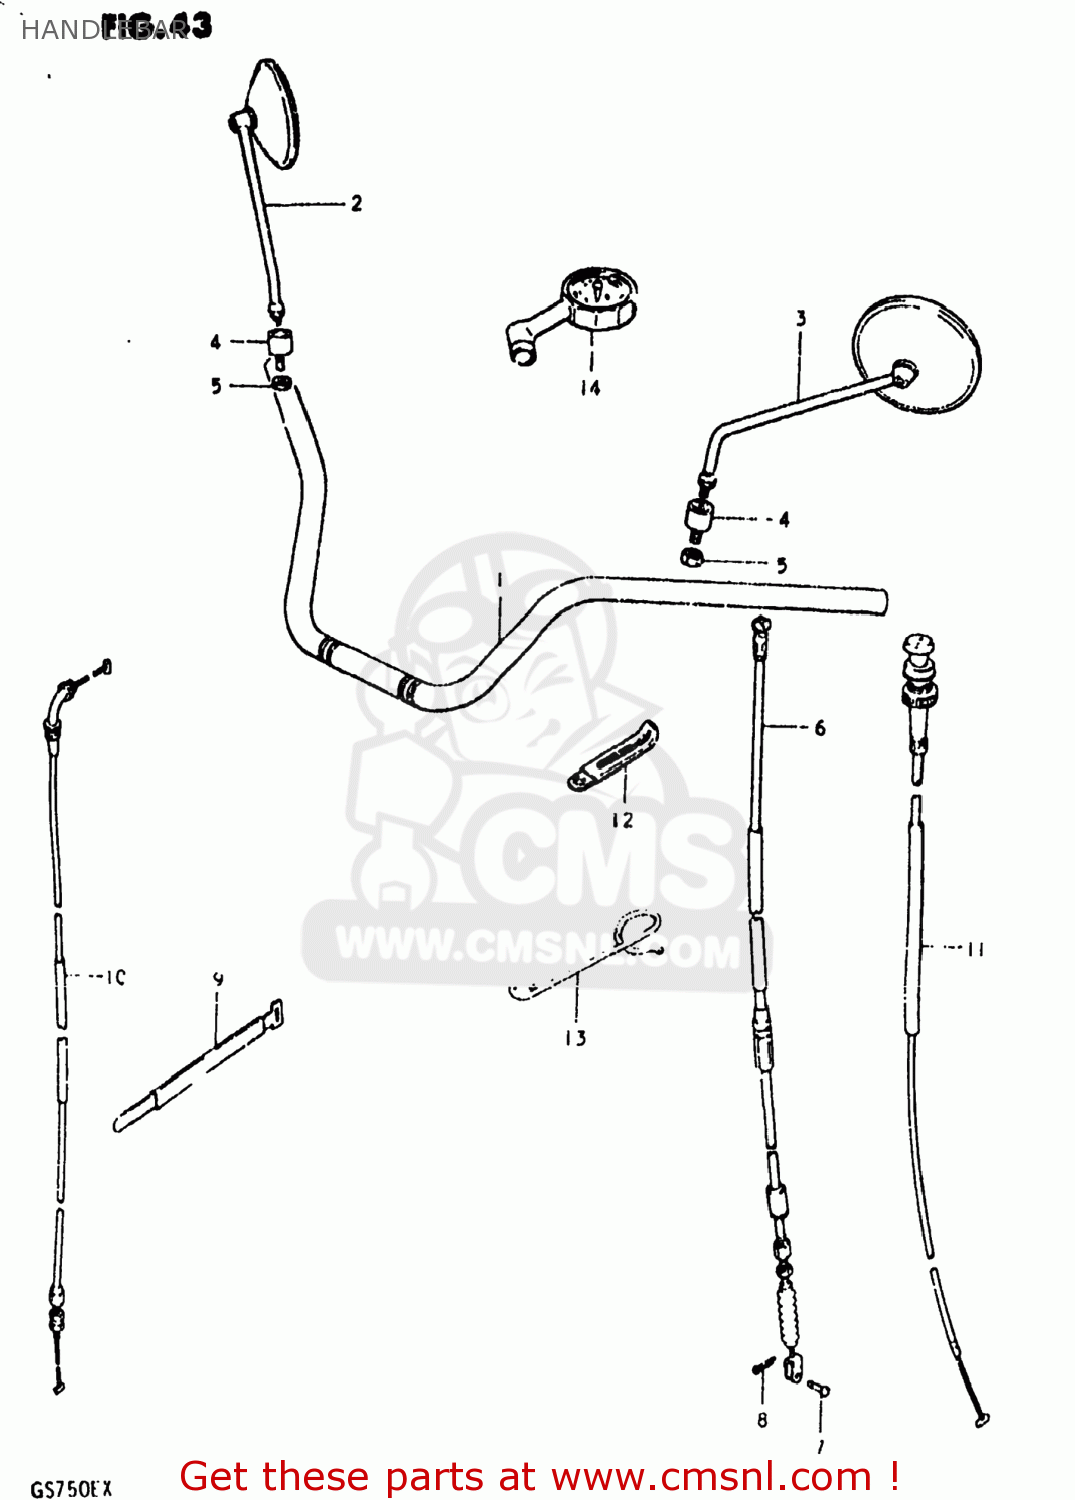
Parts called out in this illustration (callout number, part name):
1	HANDLEBAR
2	MIRROR ASSEMBLY,RIGHT
3	MIRROR ASSEMBLY,LEFT
4	CUSHION,REAR VIEW MIRROR
5	NUT
6	CABLE ASSY,CLUTCH
7	PIN(L:15)
8	PIN
9	CLAMP
10	CABLE ASSEMBLY,THROTTLE
11	CABLE ASSEMBLY,STARTER
12	CLAMP
13	GUIDE,CLUTCH CABLE
14	GAUGE ASSY,AIR PRESSURE
